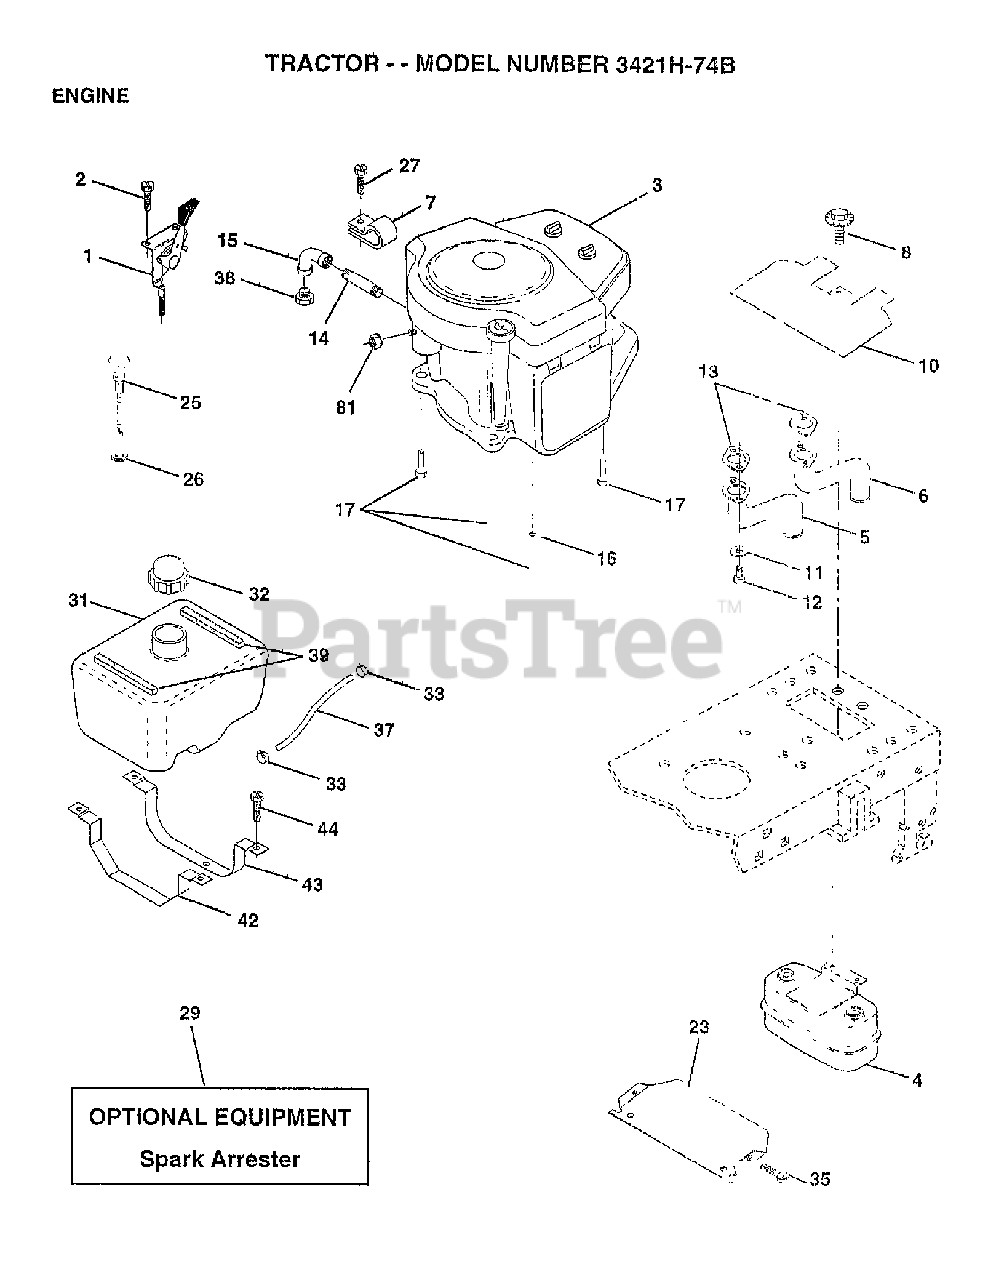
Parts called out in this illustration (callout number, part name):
1	DECK W/DECALS 72" HUS
3	Poulan TBD
4	MUFFLER.TWIN.CYL.LOW.TONE
5	EXHAUST ASM. LEFT
6	EXHAUST ASM. RIGHT
10	SHIELD HEAT LT
14	NIPPLE, PIPE 3/8NPT X 4-1/2
15	ELBOW
16	LOCKWASHER
25	CONTROL.CHOKE.51.00.BLK.W/BEND
26	NUT KEPS 3/8 - 24 UNF
27	SCREW.TT.#10-32X.5.3/8.FLANGE
29	KIT.SPARK ARRESTOR(392390 B&S)
33	HOSE CLAMP
35	Screw, Lt
37	LINE FUEL 7.5"
